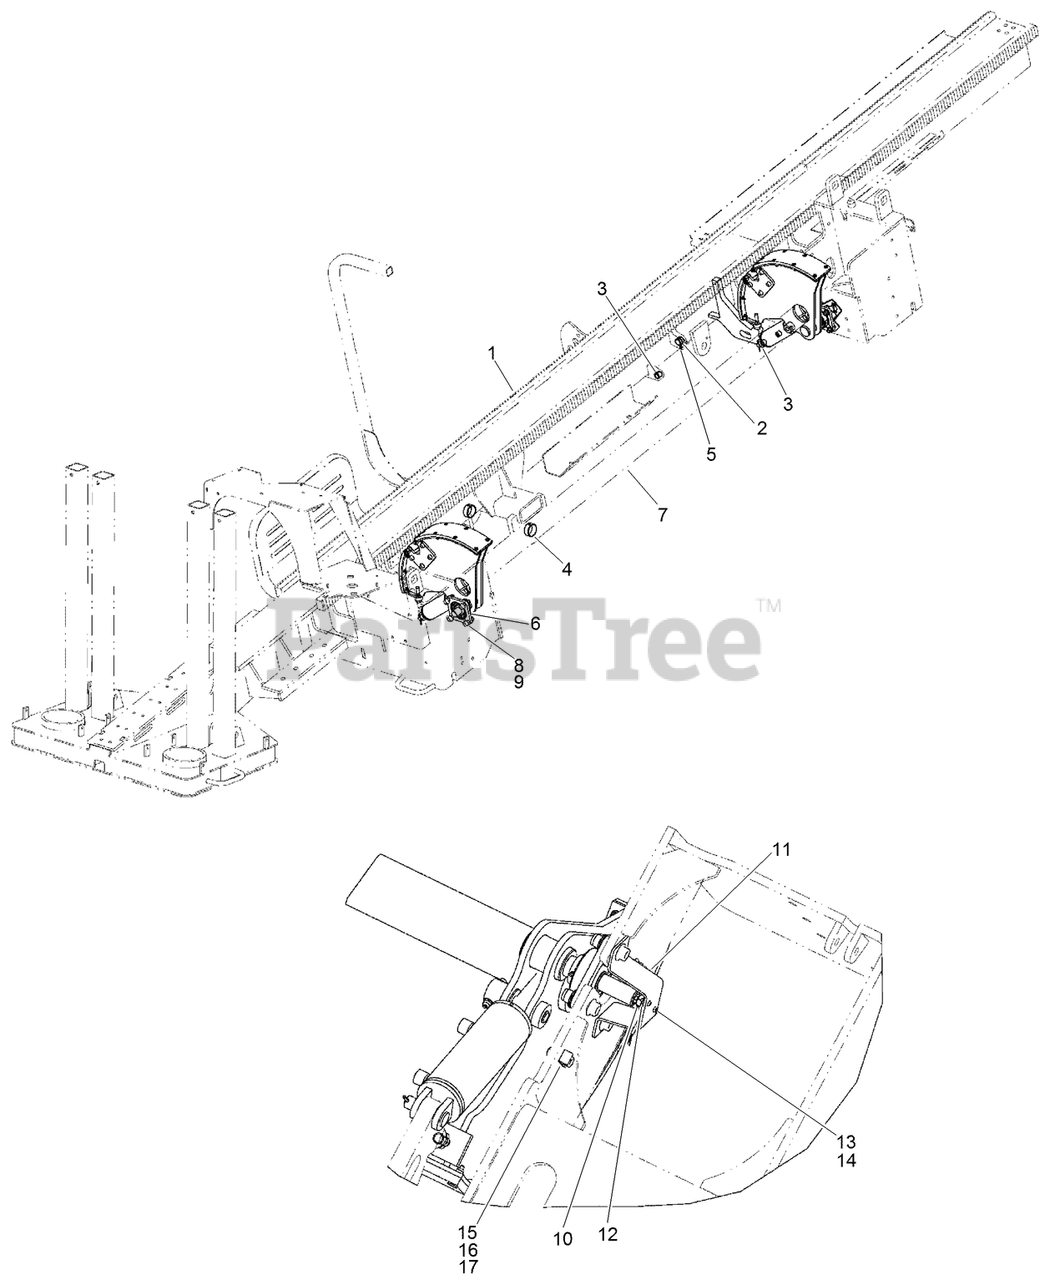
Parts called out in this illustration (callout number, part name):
1	WELDMENT - Thrust Frame
2	SPRING BUSHING - 1.00 ID x 1.25 OD x 1.00 Long
3	BUSHING-SPRING
4	SPRING BUSHING - 2.00 ID x 2.25 OD x 1.00 Long
5	FITTING-Lube 1/4-28 Tpr SAE-LT .54 Long
6	BEARING-FLANGED Y, SQUARE
7	ASSEMBLY - Rod Loader
8	SCREW-HHF
9	NUT-HHF, LOCK
10	JAM NUT - M10 - 1.0
11	PLATE - Mounting
12	SENSOR - Rotary
14	NUT-#8-32 KEPS
15	CLAMP - Insul 12.7 mm 3/8 in Bolt ZND
16	NUT-FLANGE, NYLOCK
17	SCREW-HH
